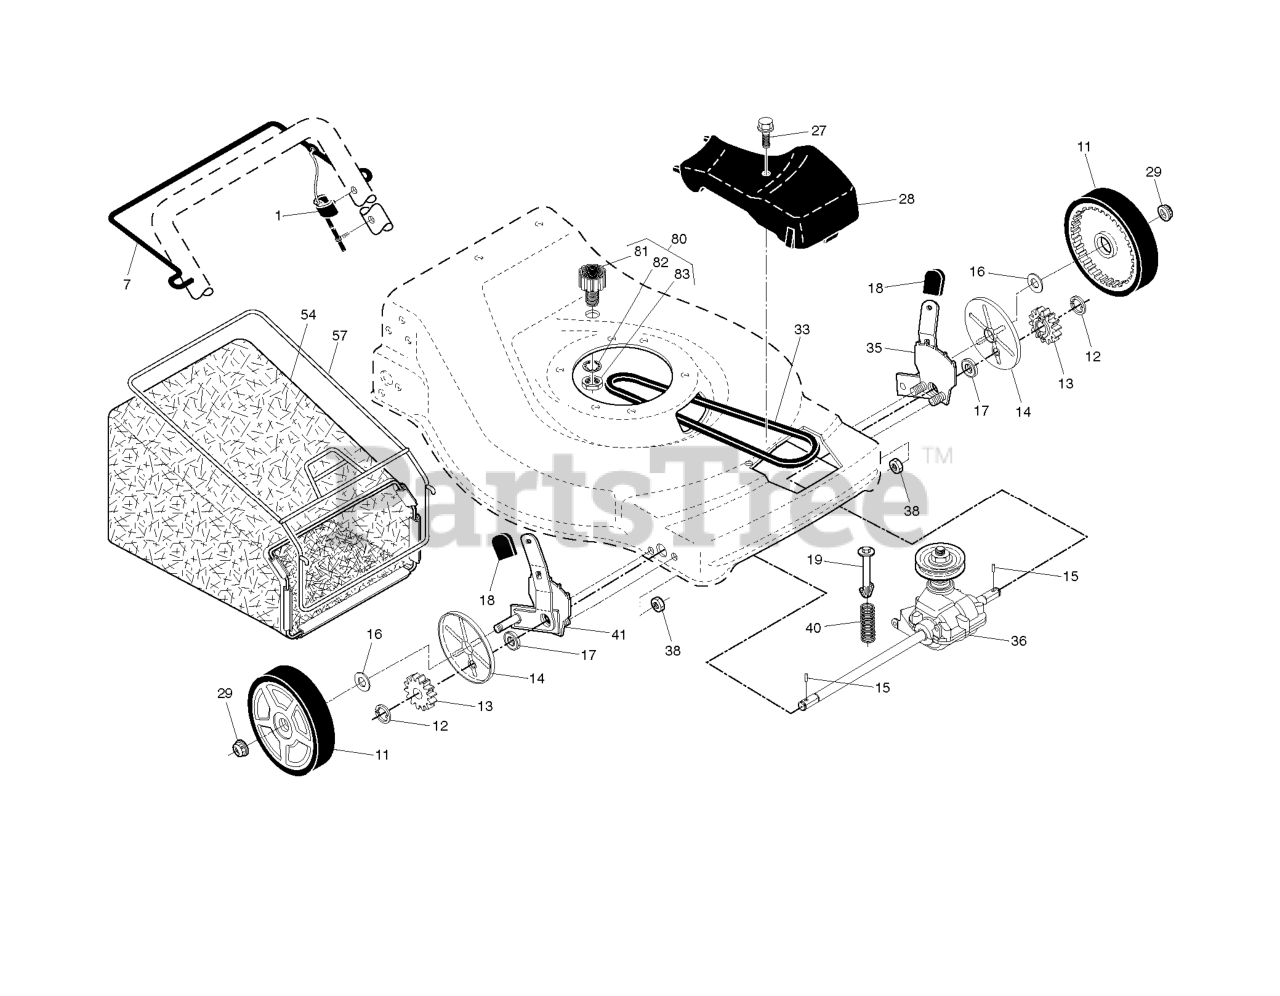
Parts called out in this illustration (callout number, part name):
1	CONTROL.DRIVE.S/SPEED.FWGD
7	BAIL.CONT.DR.S/S.ROUND.ORG
11	WHEEL.8X1.75.H3SPK.RAD3.GY.BU3
12	E-RING 7/16 RE
13	PINION.14.TEETH.FGD
14	COVER.DUST.WHEEL
15	PAWL, DRIVE
16	WASHER FLUT
17	BEARING.ASM.
18	SELECTOR KNOB
19	SPRING RETAINER
27	SCREW, HEX HD TAPPING #10-24 1
28	COVER.DRIVE.TORUS.B&S.MOLDED
29	NUT.HEX.FLANGE.3/8-16.LO(3 2)
33	BELT THERM .32
35	KIT ADJUSTER ASM.438151.
36	TRANSMISSION.22.FGD/W/PULLEY
38	LOCKNUT.NYLOC.1/4-20
40	SPRING.EXTENSION
41	KIT ADJUSTER ASM.438148
54	GBAG.83230247T.SIL.HUSQ.BLU
57	FRAME.GBAG.22.EZ.EMPTY.SC
80	KIT.WASH-OUT.PORT
81	FITTING, HOSE, WATER WASHOUT
82	WASHER.LOCK.INTERNAL.TOOTH
83	LOCKNUT.HEX.WITH.O-RING
